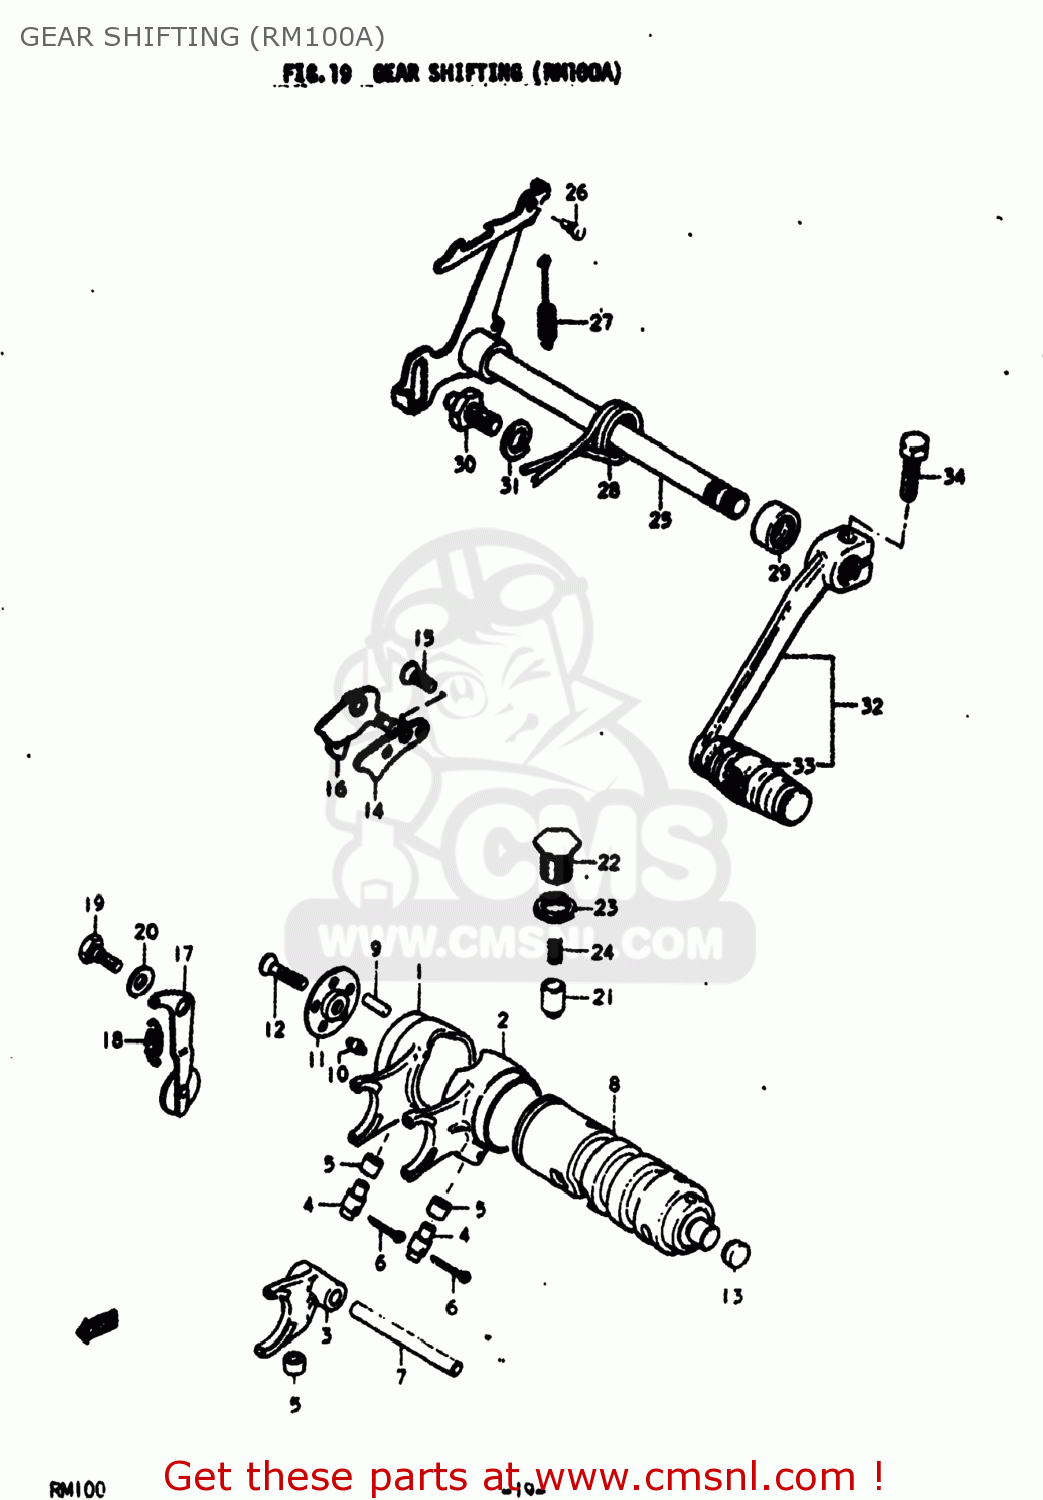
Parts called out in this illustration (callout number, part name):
1	FORK,GEAR SHIFT NO.1
2	FORK,GEAR SHIFT NO.2
3	FORK,GEAR SHIFT NO.3
4	PIN
5	SPACER
6	PIN 25X20
7	SHAFT,GEAR SHIFT FORK
8	CAM,GEAR SHIFT
9	ROLLER(4X13.8)
10	PIN
11	RETAINER,GEAR SHIFT CAM DR PIN
12	SCREW
13	PLUG
14	GUIDE,GEAR SHIFT CAM
15	SCREW
16	PAWL,GEAR SHIFT CAM STOPPER
17	STOPPER,GEAR SHIFT CAM
18	SPRING
19	BOLT(6X16.1)
20	WASHER(6.5X16X2.3)
21	STOPPER,GEAR SHIFTING
22	HOLDER,SHIFTING CAM STOPPER
23	GASKET(14X19.2X2) (NAS)
24	SPRING
25	SHAFT,GEAR SHIFT
26	PIN
27	SPRING
28	SPRING
29	OIL SEAL
30	STOPPER,GEAR SHIFT ARM
31	LOCK WASHER
32	LEVER ASSEMBLY,GEAR SHIFTING
33	RUBBER,GEAR SHIFT PEDAL
34	BOLT
